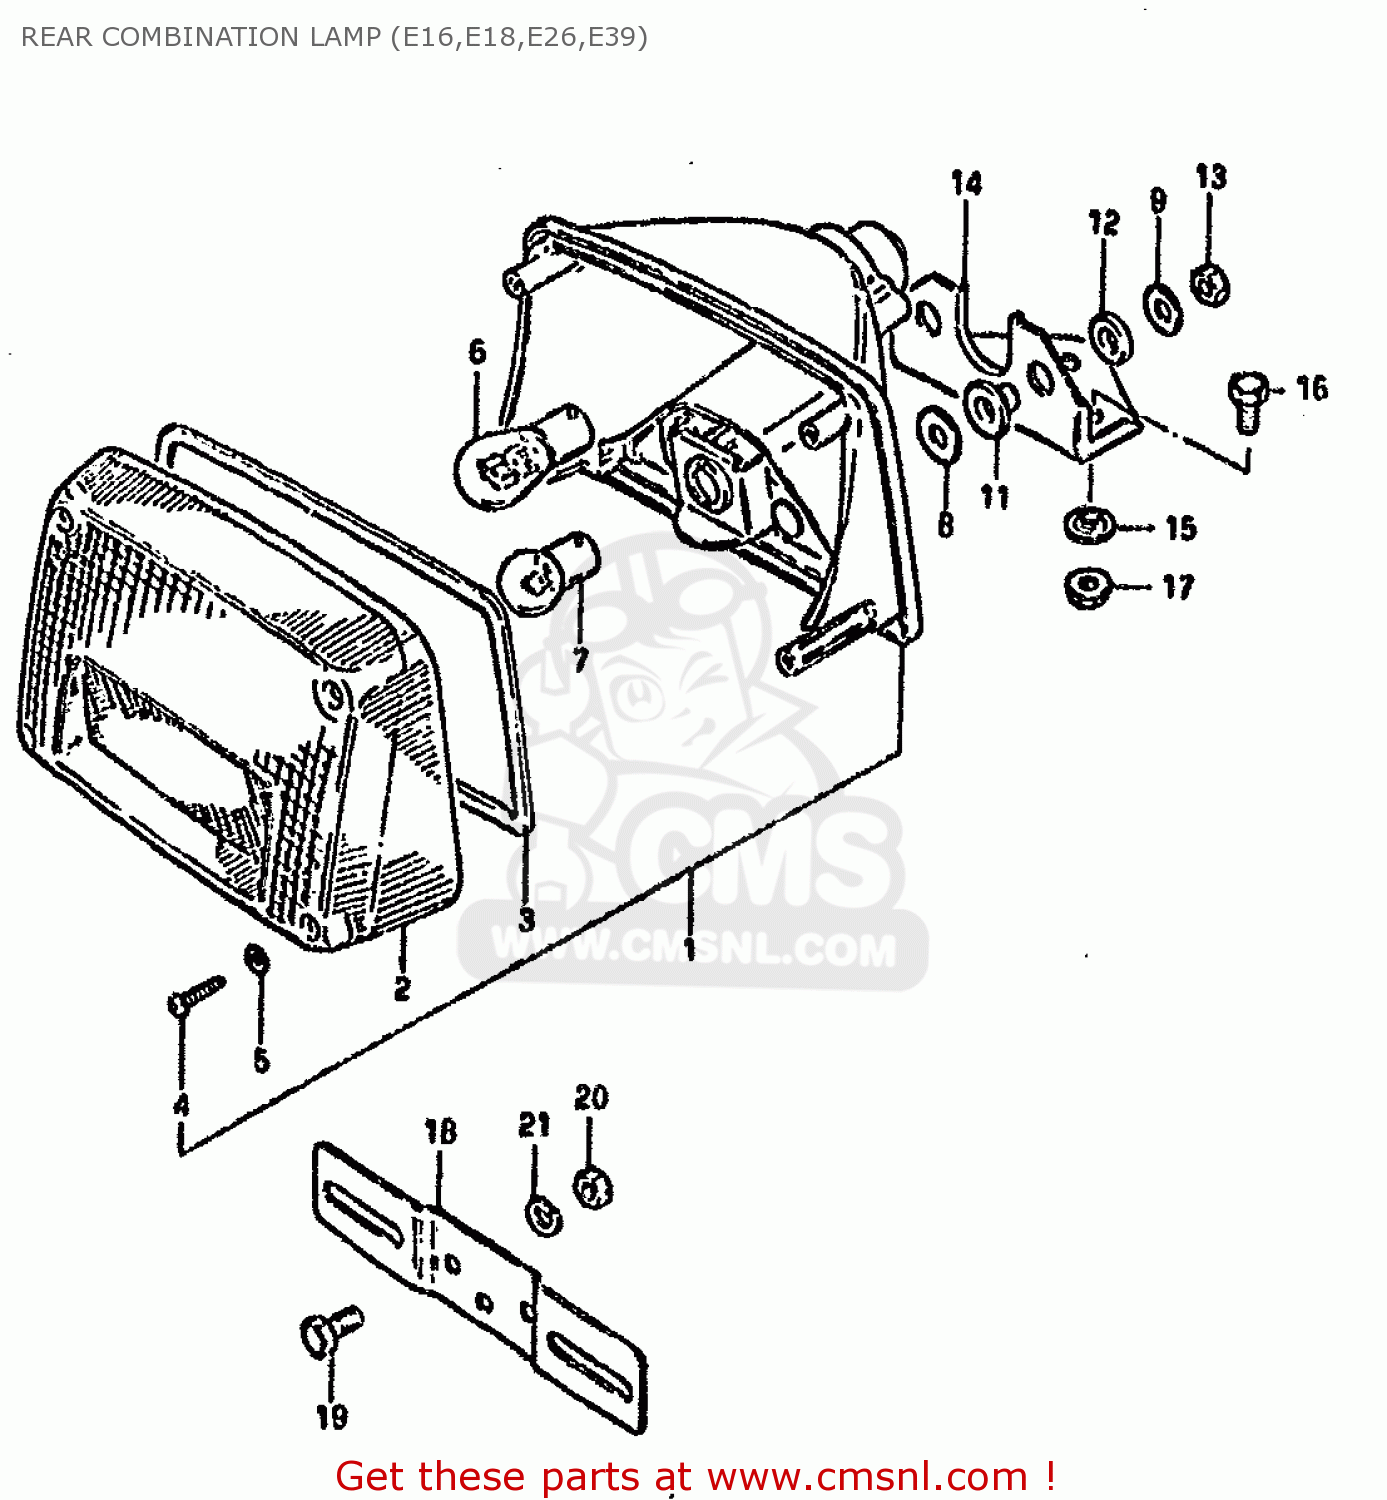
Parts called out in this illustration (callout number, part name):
1	LAMP ASSY, TAIL
2	LENS,RR COMBI
3	GASKET (NAS)
4	SCREW,REAR COMBINATION LAMP
5	GASKET (NAS)
6	BULB 12V21/5W
7	BULB
8	WASHER
9	WASHER(6,5X22X1.6)
10	SPACER(6.1X9X7.5)
11	CUSHION
12	CUSHION
13	NUT 6MM
14	BRACKET,RR COMBINATION LAMP
15	WASHER
16	BOLT, UPPER
17	NUT 6MM
18	PLATE,RR LICENSE
19	BOLT
20	NUT
21	LOCK WASHER
